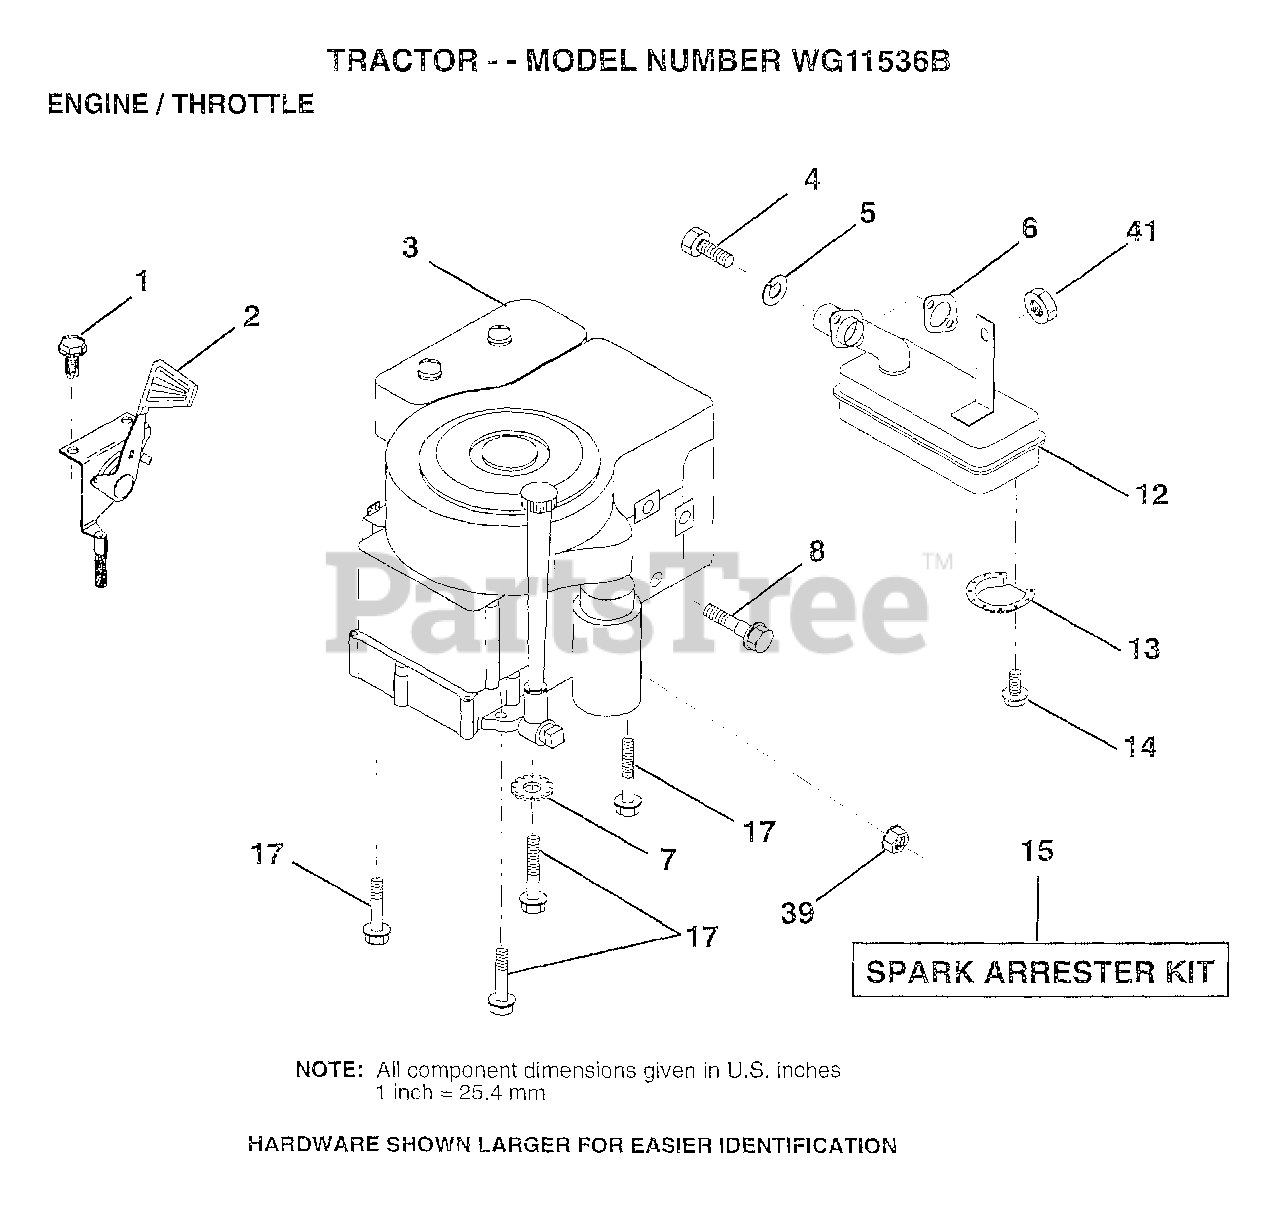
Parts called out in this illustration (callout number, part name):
1	SCREW.1/4-20X1/2
2	"CONTROL,THROTTLE"
4	SCREW HEX HD CAP
5	LOCKWASHER
6	GASKET ENG 1 313 LD TIN PLATED
7	LOCKWASHER
8	SHOULDER BOLT ST
12	MUFFLER-TECH 13HP
13	DEFLECTOR.222573
17	SCREW LT
39	NUT
41	"NUT HEX,LOCK,FLAN"
